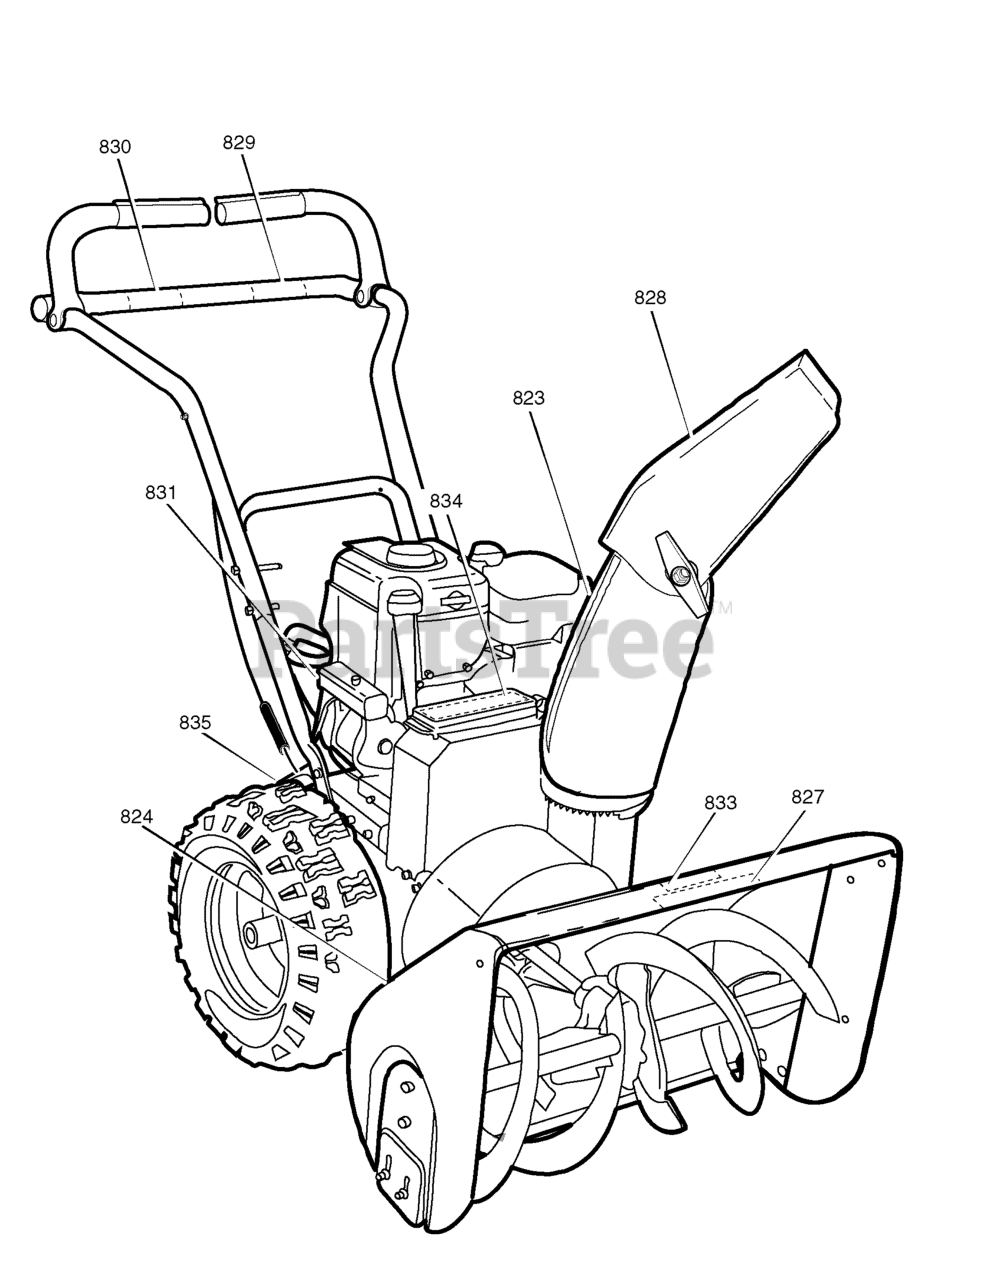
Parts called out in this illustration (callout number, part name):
823	DECAL, DANGER CHUTE HAND
824	DECAL, DANGER FOOT
827	DECAL, 1150/24 CRAFTSMAN AUGER
828	DECAL, THROWN OBJECTS
829	DECAL, DRIVE CLUTCH
830	DECAL, AUGER CLUTCH
831	DECAL, GEAR SELECTOR
833	DECAL, CLEAN & CLEAR BRUSH
834	DECAL, TOOLBOX INFORMATION
835	DECAL, ID PLATE
